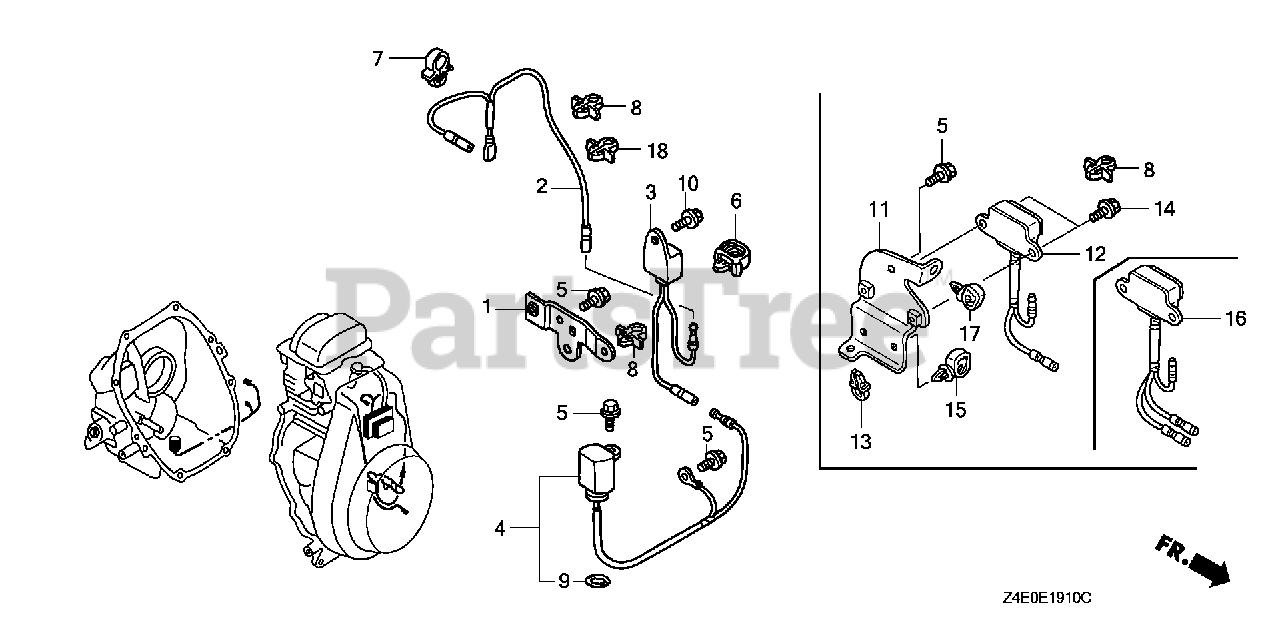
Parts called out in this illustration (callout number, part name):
4	SWITCH ASSY., OIL LEVEL
5	BOLT, FLANGE (6X14) (CT200)
7	CLIP, CABLE (6MM) (WHITE)
8	CLIP A, CABLE (3.8MM BLACK) (NIFCO)
9	O-RING (11.8X2.4)
